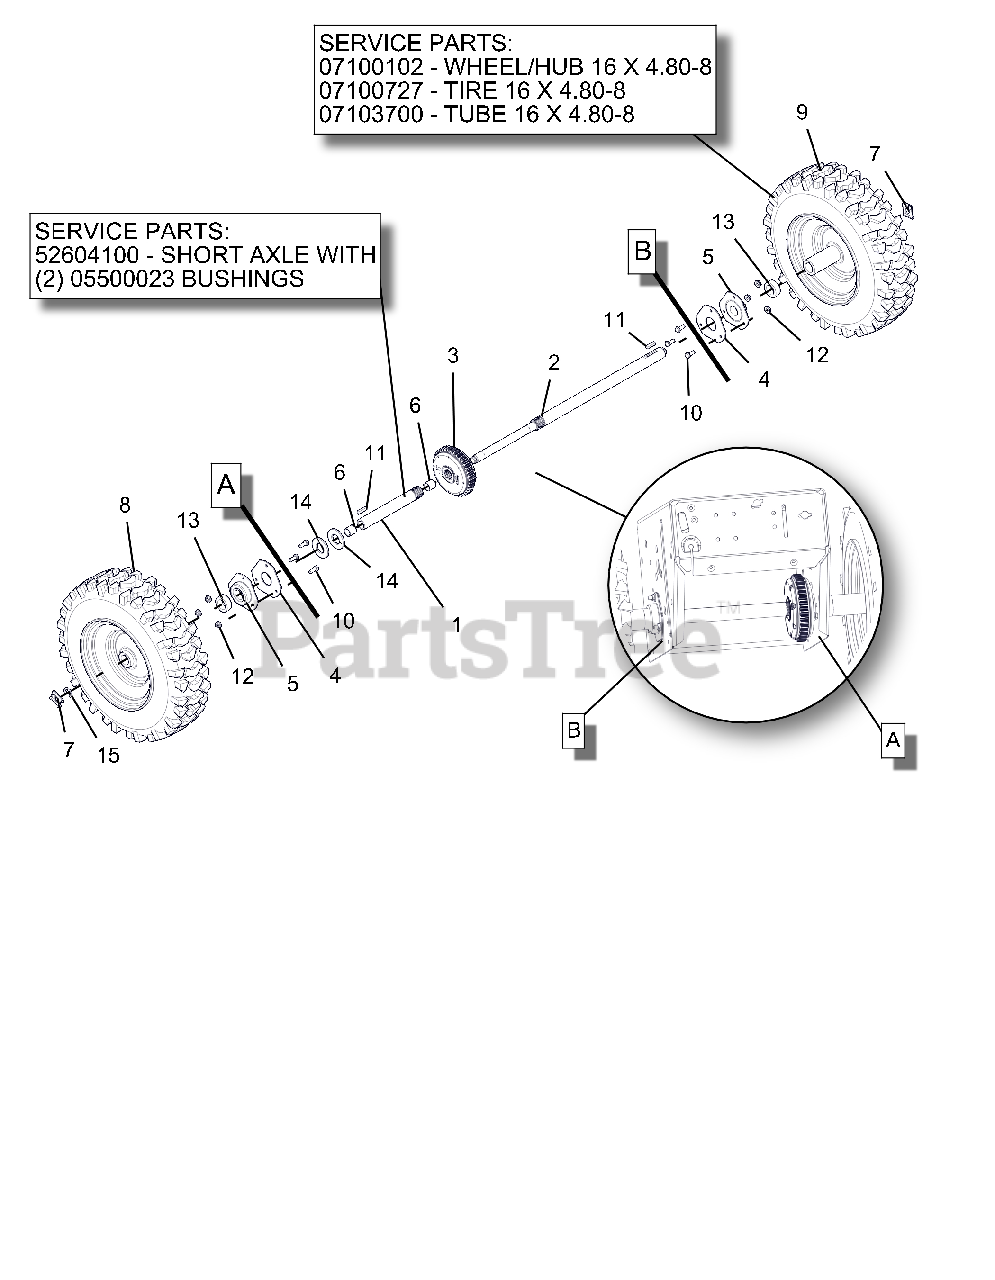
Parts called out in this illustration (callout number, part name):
1	AXLE, SHORT-PRO AUTO DIFF
1	AXLE, SHORT-AUTO W/BUSHINGS
1	BSHG-SLV .706X.764X.75 BRZ
2	AXLE, LONG-PRO AUTO DIFF
3	DIFFERENTIAL, AUTOMATIC
4	PLATE, BEARING SPACER
5	BRG-FLG 1.003/1.000 3 BOLT
6	BSHG-SLV .706X.764X.75 BRZ
7	CLIP, SNAP .625 DIA
8	TIRE/WHEEL,RH 16X4.8-8 DIFF T2
9	TIRE/WHEEL,LH 16X4.8-8 DIFF T2
9	HUB, WHEEL - 16X4.8-8 DIFF
9	TIRE, 4.80-8 K478
9	TUBE
10	@BLT-HEX .25-20X.75 GR5 YWZC
11	KEY-RECT .25X.188X1.00
12	@NUT-LK-CTR-FLG .25-20 YWZC
13	SPACER, PRO AXLE BEARING
14	WSHR-FL-STL- 1.062X2.0X.134 YZ
15	RG-RTNG-EXT .625X.042
